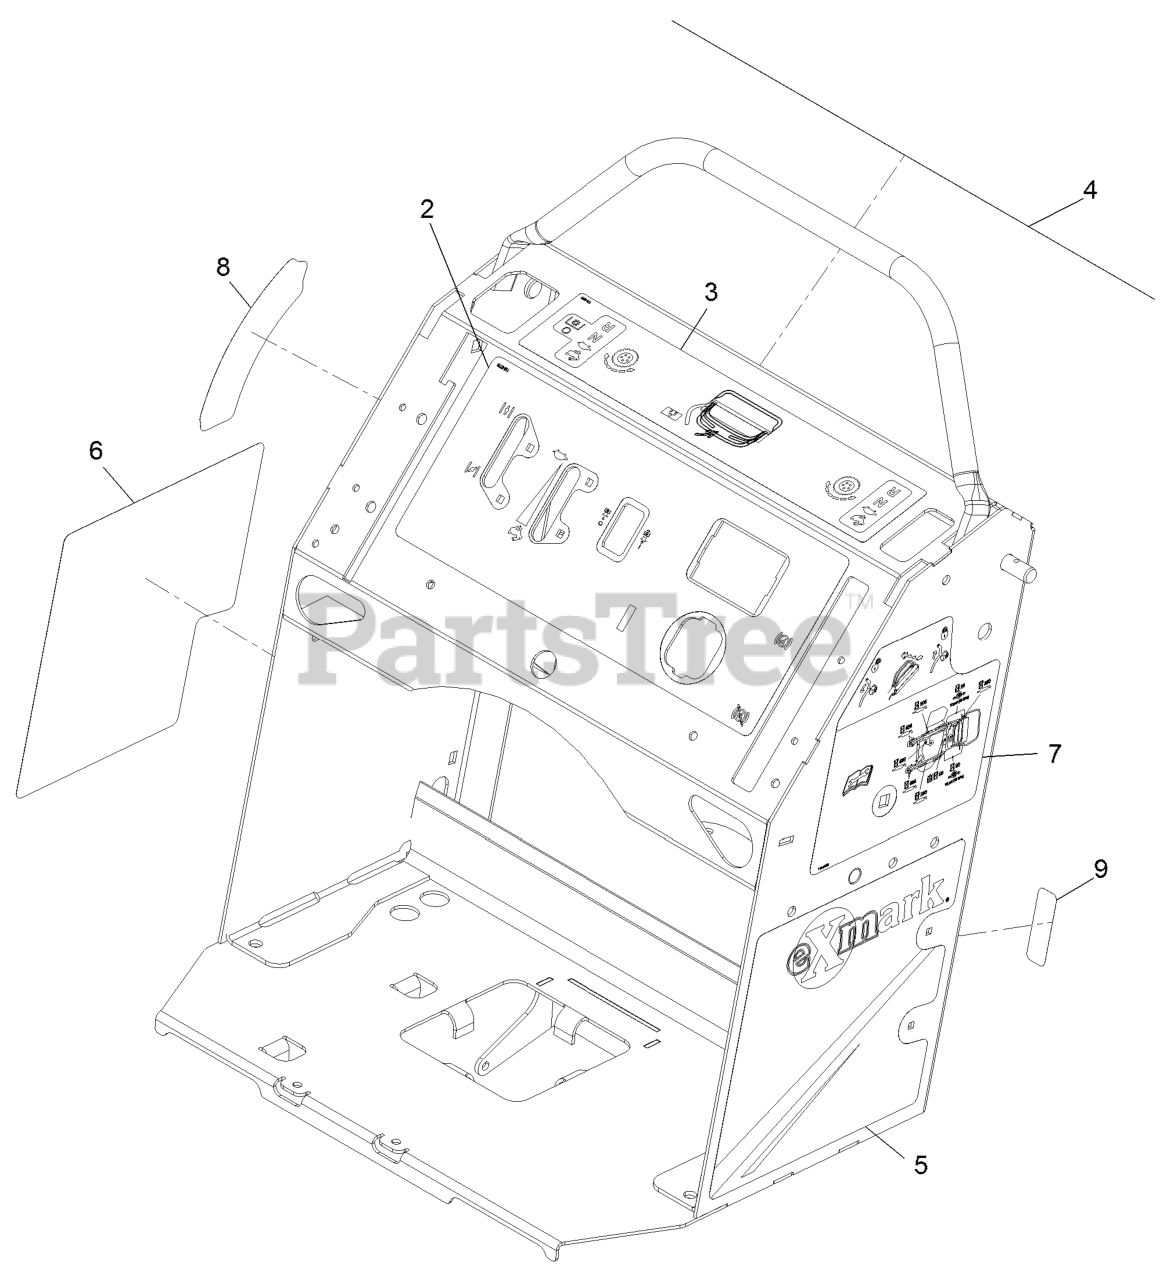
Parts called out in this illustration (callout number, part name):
2	DECAL-CONTROL PANEL
3	DECAL-MOTION CONTROL
4	DECAL-WARNING
5	DECAL-LH PANEL
6	DECAL-RH PANEL
7	DECAL-SERVICE AID
8	DECAL-HEIGHT OF CUT
9	DECAL-FUSE
